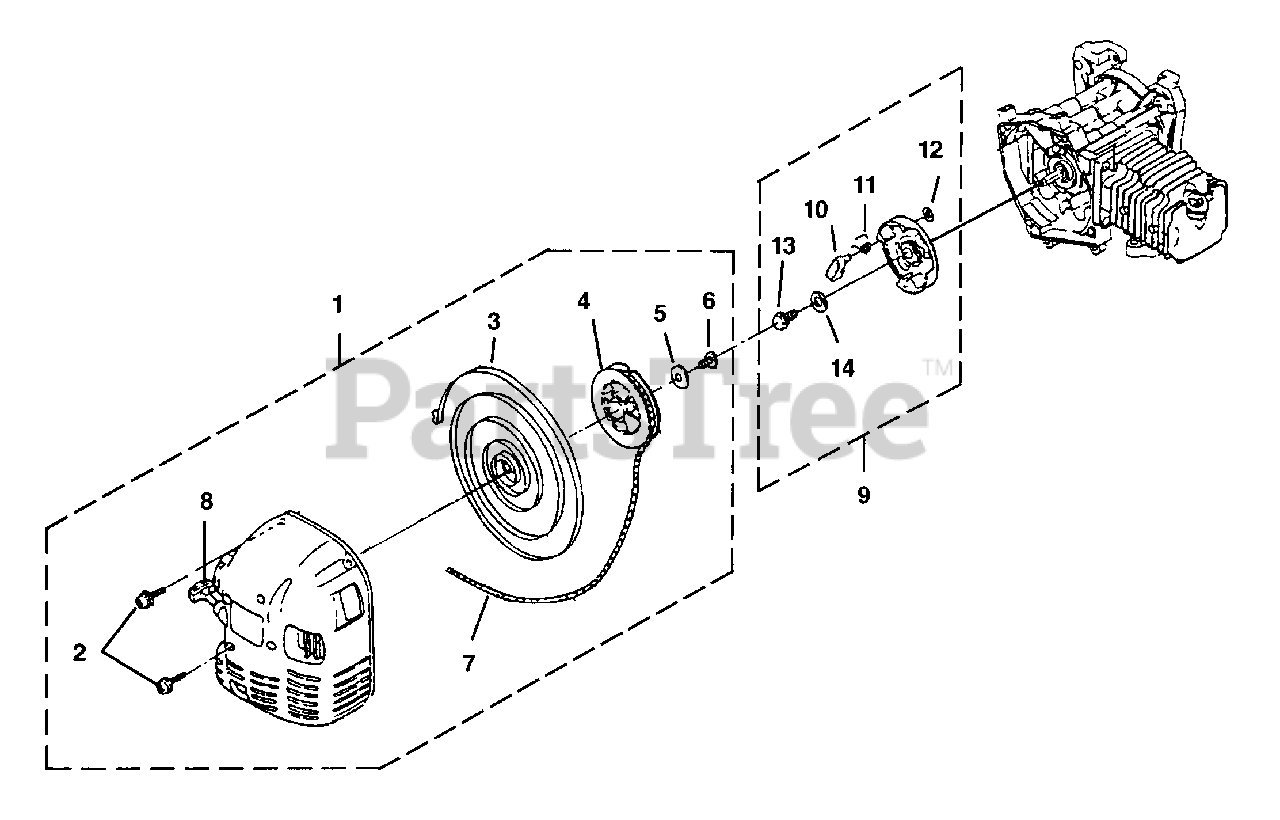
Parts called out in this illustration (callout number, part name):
1	STARTER COMPLETE
2	SCREW-Socket Hd (M5 x 20 W SW)
6	SCREW (M5 x 12)
7	ROPE-Starter
9	STARTER CUP ASSEMBLY
11	SPRING-Return
13	BOLT ASSEMBLY (M6 x 16)
14	WASHERS (M5)
